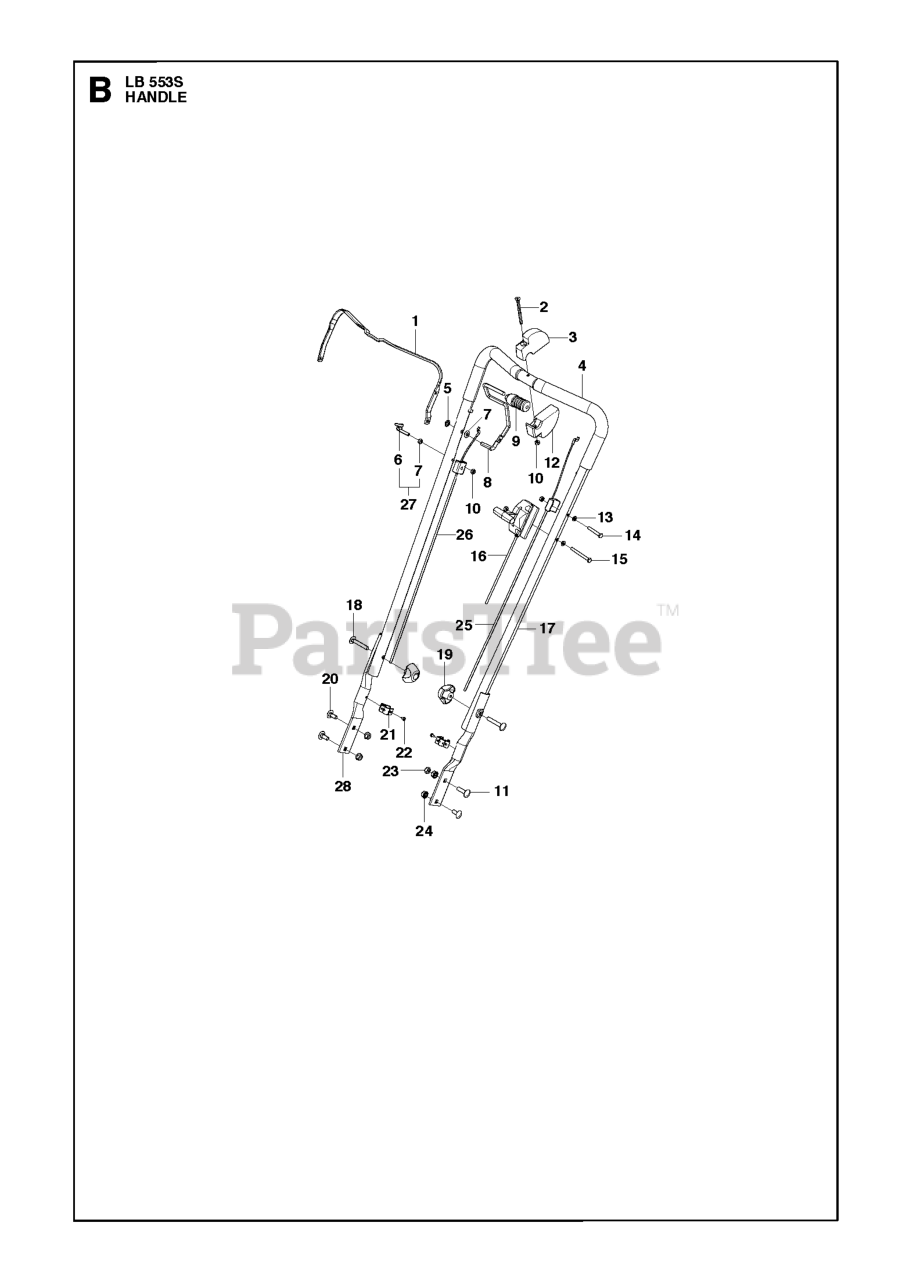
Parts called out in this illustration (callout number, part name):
3	WEIGHT VIBRATION ABSORBER UPPE
5	WASHER STARLOCK WITH CAP
8	LEVER M53 / M48
9	KNOB M53S / M48S HUSQVARNA GRE
10	NUT FLANGE - M6
12	WEIGHT LOWER
15	SCREW
16	THROTTLE CONTROL
17	HANDLE UPPER WITH HOLE
19	HANDLE M53 / M48
22	SCREW RXS B8X9.5
23	LOCKNUT M8
25	CABLE BRAKE BREAK M53
27	STARTER ROPE GUIDE KIT
